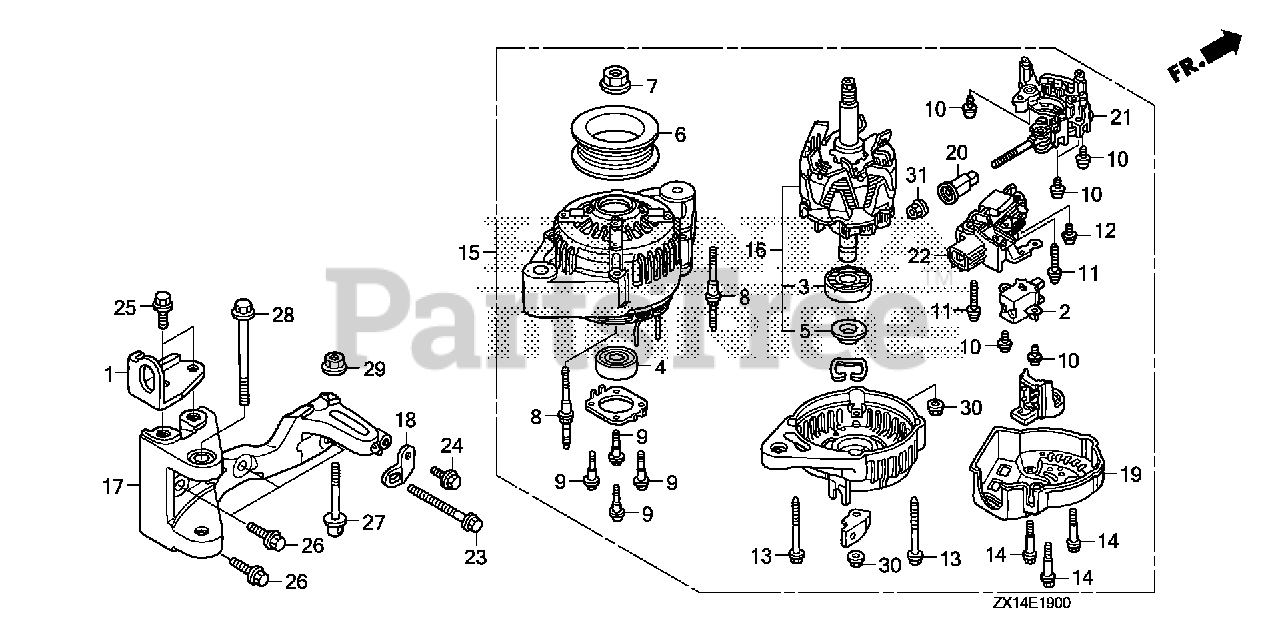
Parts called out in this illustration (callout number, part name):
1	HANGER B, ENGINE
2	HOLDER ASSY., BRUSH
3	BEARING, RR.
4	BEARING, FR.
5	COVER, BEARING
7	NUT, PULLEY LOCK
8	BOLT, STUD
10	SCREW-WASHER
11	SCREW-WASHER (4X25)
13	BOLT-WASHER
15	ALTERNATOR ASSY.
16	ROTOR ASSY.
17	BRACKET, ALTERNATOR
18	STAY, ALTERNATOR
19	END COVER, RR.
20	BUSH, INSULATION
21	RECTIFIER ASSY.
22	REGULATOR ASSY.
23	BOLT, SPECIAL ADJUSTER
24	BOLT, FLANGE (6X16)
25	BOLT, FLANGE (8X20)
26	BOLT, FLANGE (8X28)
27	BOLT, TENSIONER
28	BOLT, FLANGE (10X80)
29	NUT, FLANGE (8MM)
30	NUT-WASHER (5MM)
31	NUT, HEX. (6MM)
